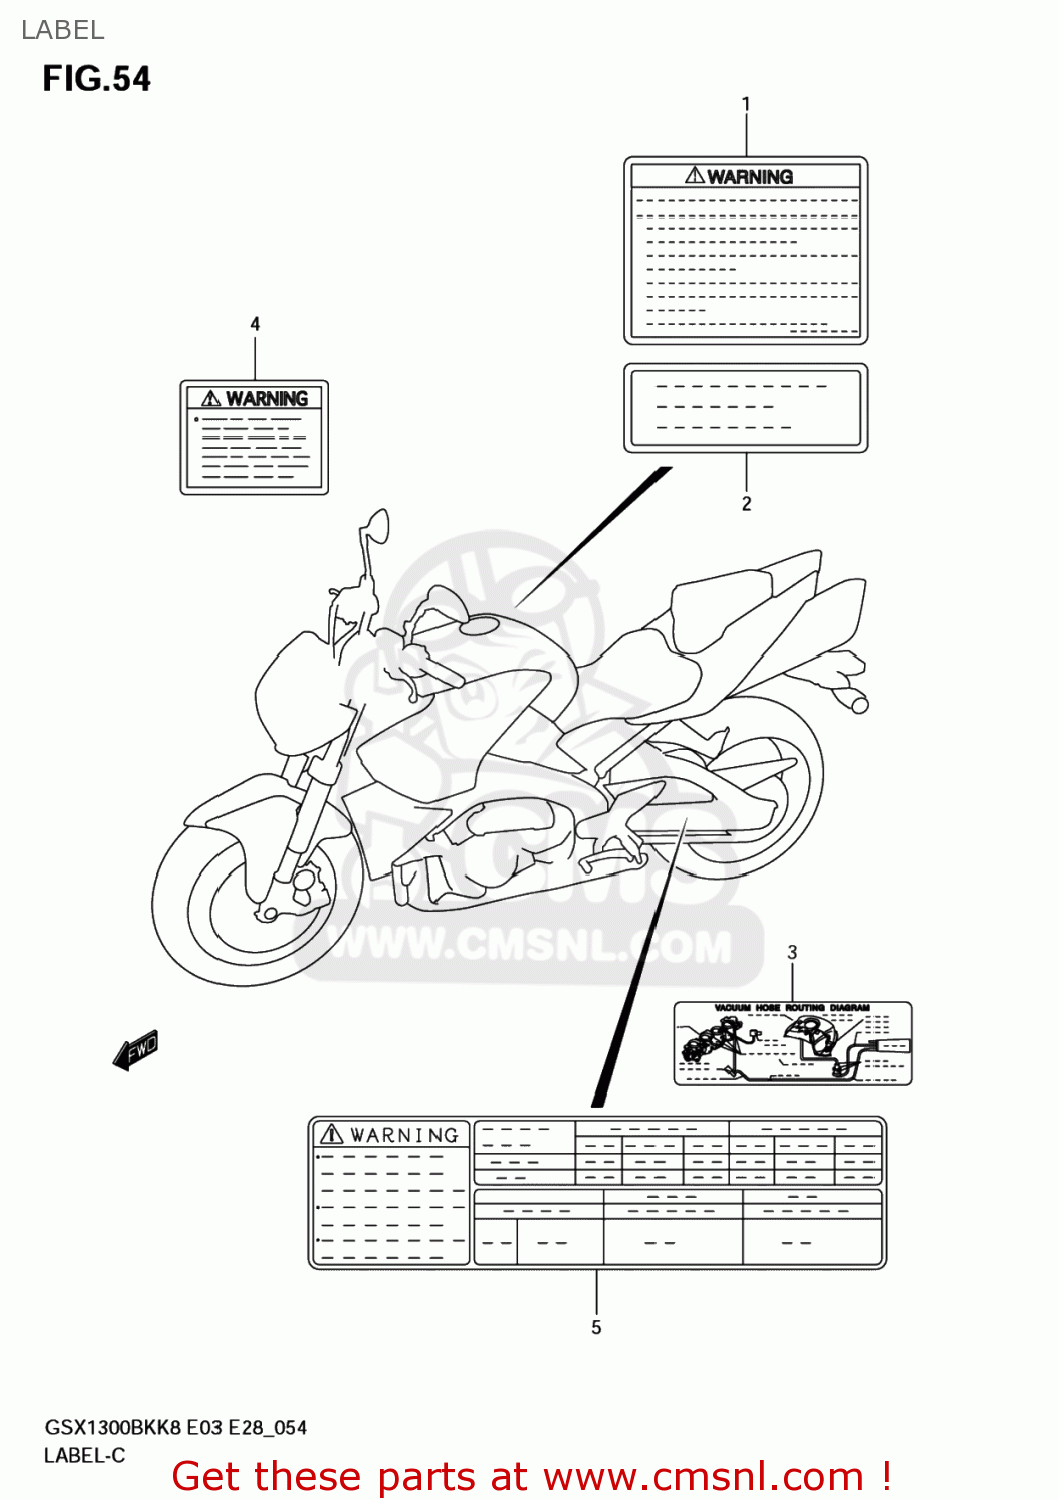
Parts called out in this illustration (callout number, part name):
1	LABEL,GENERAL WARNING
2	LABEL,MANUAL NOTICE
3	LABEL,VACUUM HOSE ROUTING
4	LABEL,STEERING DAMPER
5	LABEL,TIRE INFORMATION
6	MANUAL,OWNER'S
